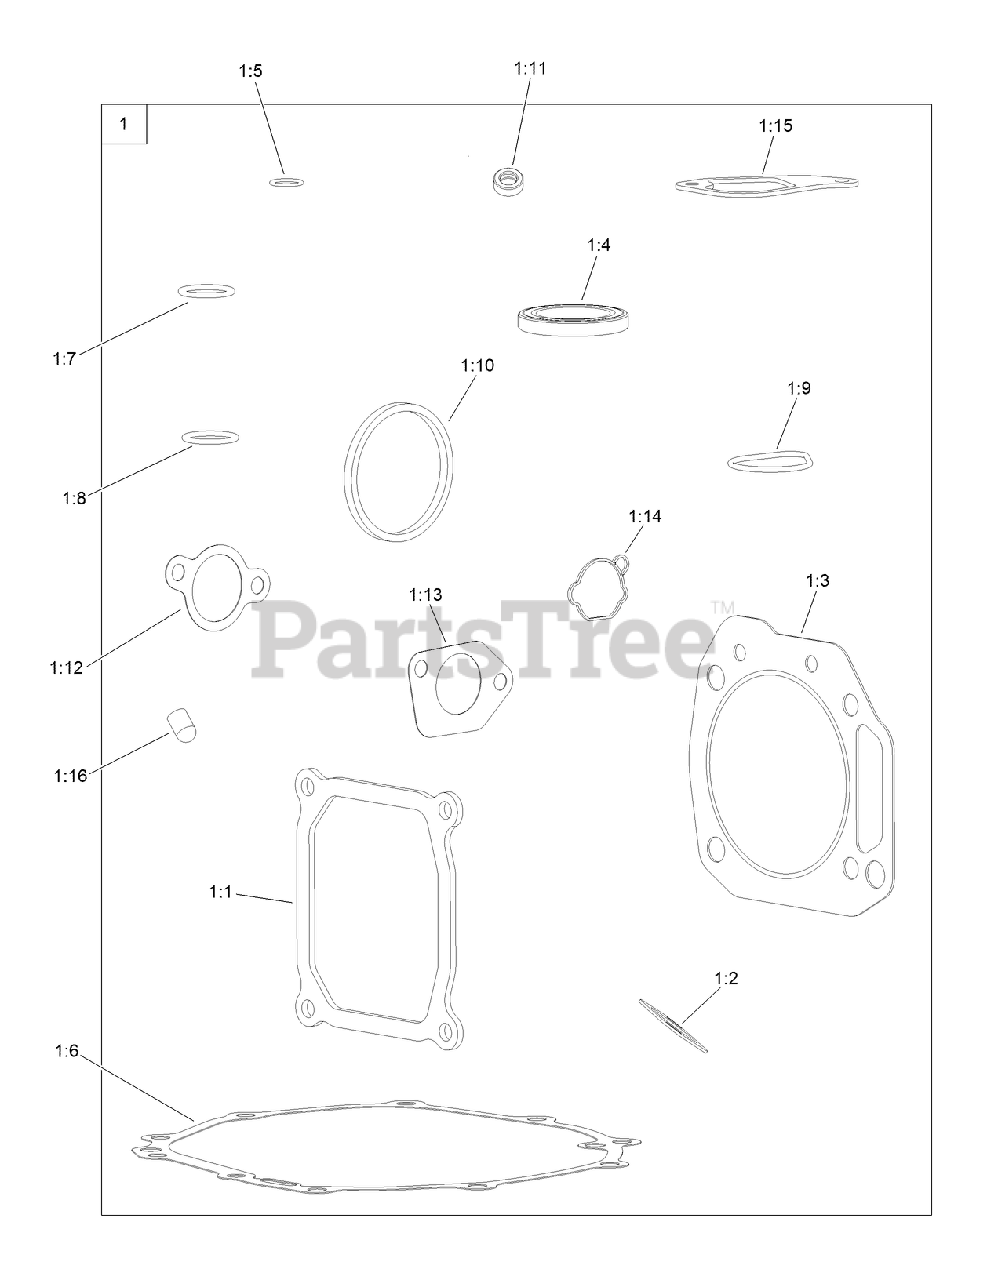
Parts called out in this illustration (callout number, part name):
1	GASKET AND SEAL KIT
1:1	GASKET-COVER, VALVE
1:2	GASKET-EXHAUST
1:3	GASKET-CYCLINDER
1:4	SEAL-OIL
1:5	O-RING
1:6	GASKET-CRANKCASE
1:7	O-RING
1:8	O-RING
1:9	SEAL-PUMP, OIL
1:10	SEAL-ADAPTOR, OIL
1:11	SEAL-OIL
1:12	GASKET-CARBURETOR
1:13	GASKET-CARBURETOR
1:14	GASKET-CARBURETOR
1:15	GASKET-BREATHER
1:16	CAP-SEAL
